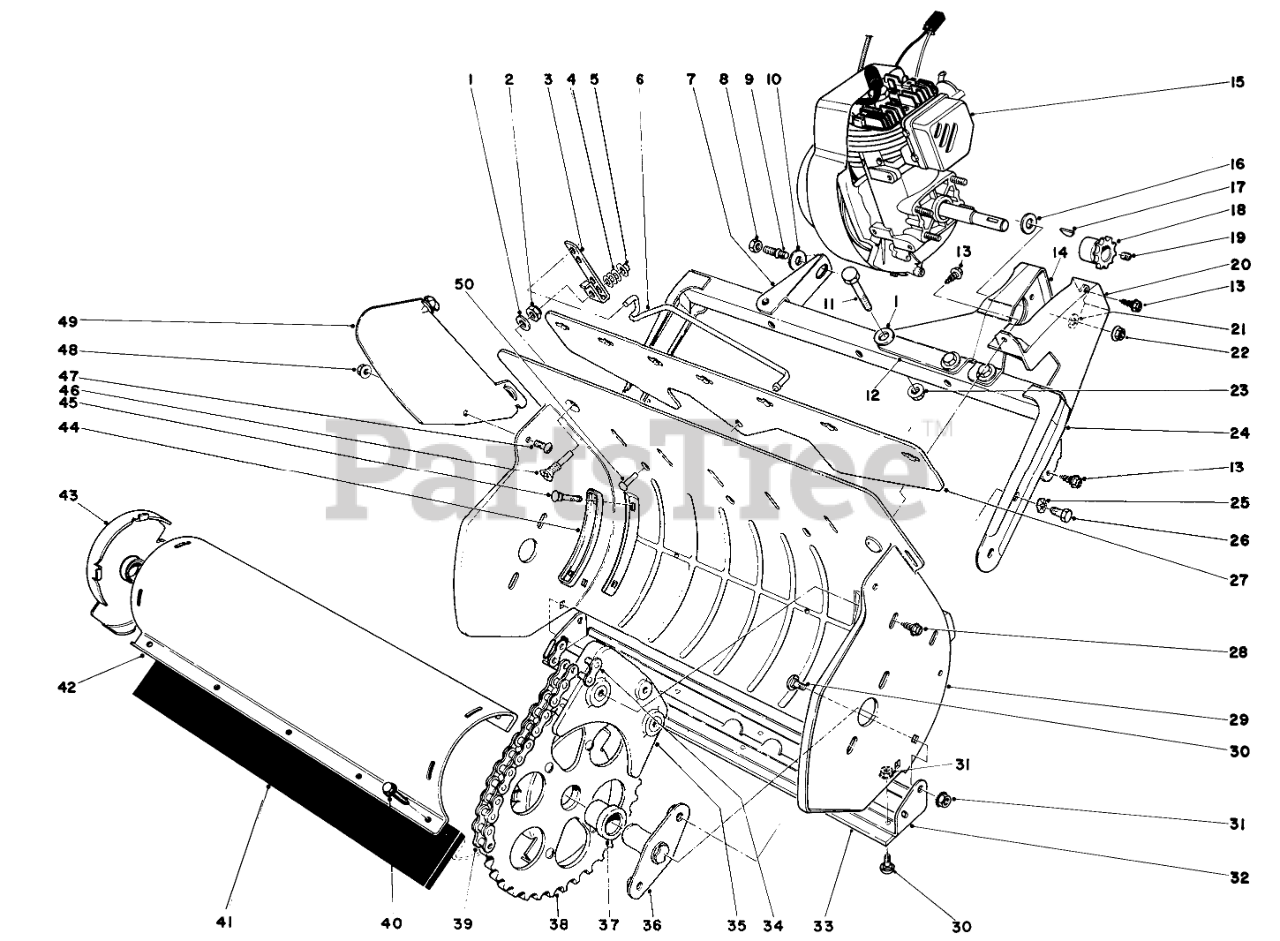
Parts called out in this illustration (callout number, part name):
1	WASHER-FLAT
2	NUT-LOCK, NI
3	Bracket Vane Adjustment
4	WASHER-FLAT
5	NUT-SPEED
6	Linkage Vane Adj.
7	Frame Bracket
8	NUT-LOCK, CONE
10	GRILLE HINGE SPACER
11	SCREW-HH
12	Engine Bracket Internal
13	SCREW-HWHTF
14	Engine Bracket External
15	Engine
16	WASHER-PLAIN
17	KEY-WOODRUFF
18	SPROCKET
19	SCREW-HSH
20	Chain Guard
21	Lockwasher
22	NUT-HF
23	NUT-LOCK, HHF
24	Frame
25	Washer
26	SCREW-HH
27	VANE MOUNT
28	Self Tapping Screw
29	Housing
30	SCREW-CARR
31	NUT-KEPS
32	Scraper Assy. (Incl. Ref. #30-31 & 33)
33	SCRAPER
34	LINK-CONNECTING, NO. 35
35	Stripper
36	ROTOR SHAFT ASM
37	ROTOR BUSHING
38	End Cap Assembly L.H. (Incl. Ref. #37)
39	ROLLER CHAIN
40	Screw
41	ROTOR BLADE
42	ROTOR SHELL
43	End Cap Assembly R.H. (Incl. Ref. #37)
44	Handle Plate
45	SCREW-CARR
46	Screw
47	SCREW-PTH
48	NUT-LOCK, FLANGE
49	Vane
50	Pop Pivot
